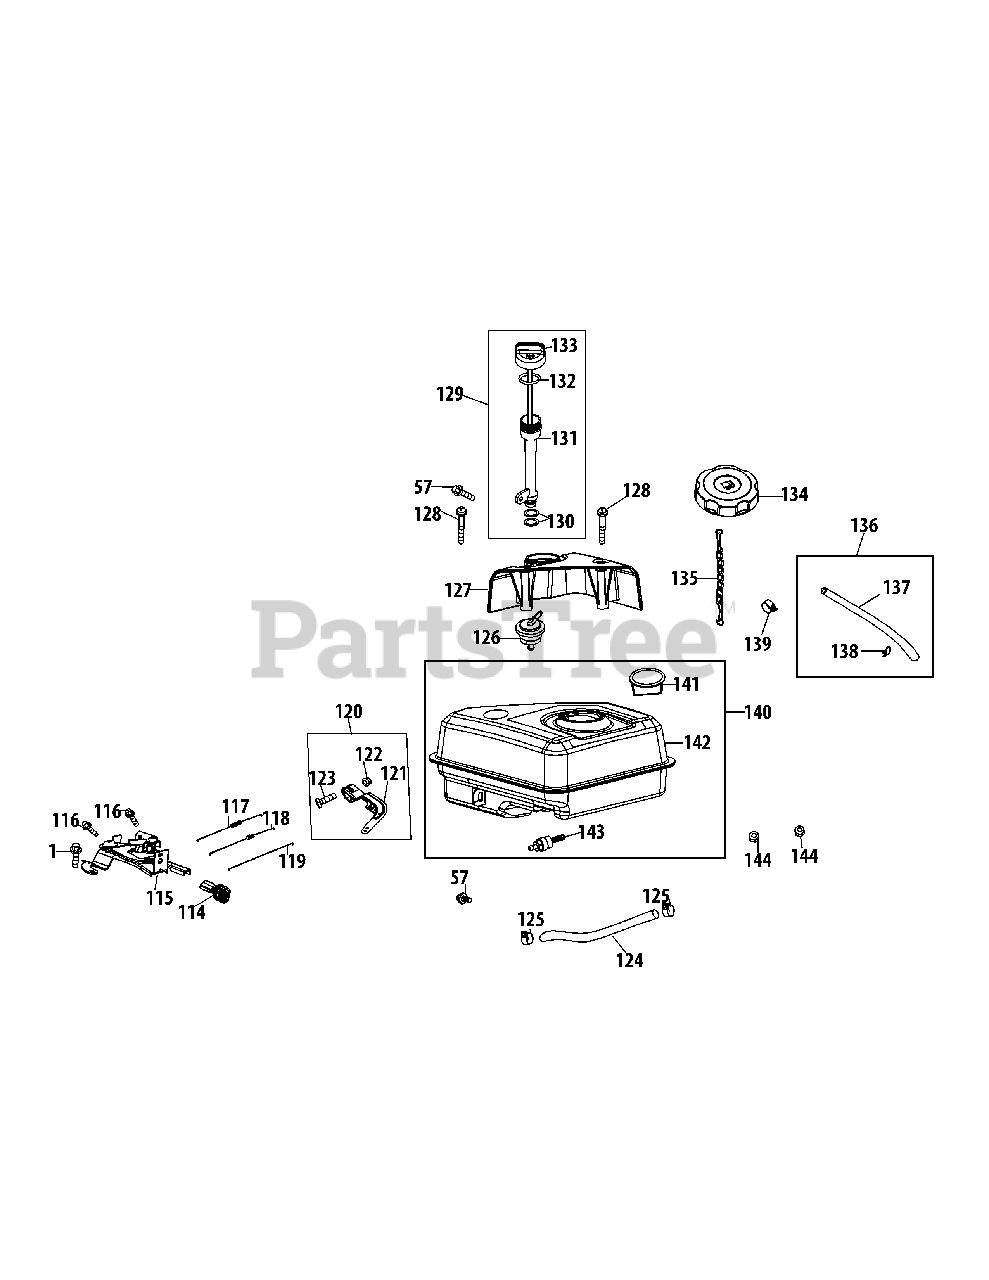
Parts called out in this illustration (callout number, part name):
1	Bolt M6×16
57	Bolt M6×12
114	Throttle Control Knob
115	Primer Bracket
116	Bolt M6×12
117	Governor Spring
118	Throttle Linkage Spring
119	Throttle Linkage
120	Governor Lever
121	Governor Arm
123	Governor Arm Bolt
125	Fuel Hose Clamp
126	Roll Over Valve
127	Dipstick Decoration Cover
129	Dipstick Assembly
130	Oil Fill Tube O-Ring
131	Oil Fill Tube
132	O-Ring 21×2.77
135	Fuel Cap Chain
136	Evap Hose Kit
137	Evap House
138	Evap House Clamp
139	Clamp, Fuel Hose
141	Fuel Filter
142	Fuel Tank Body
143	Drain Pipe
